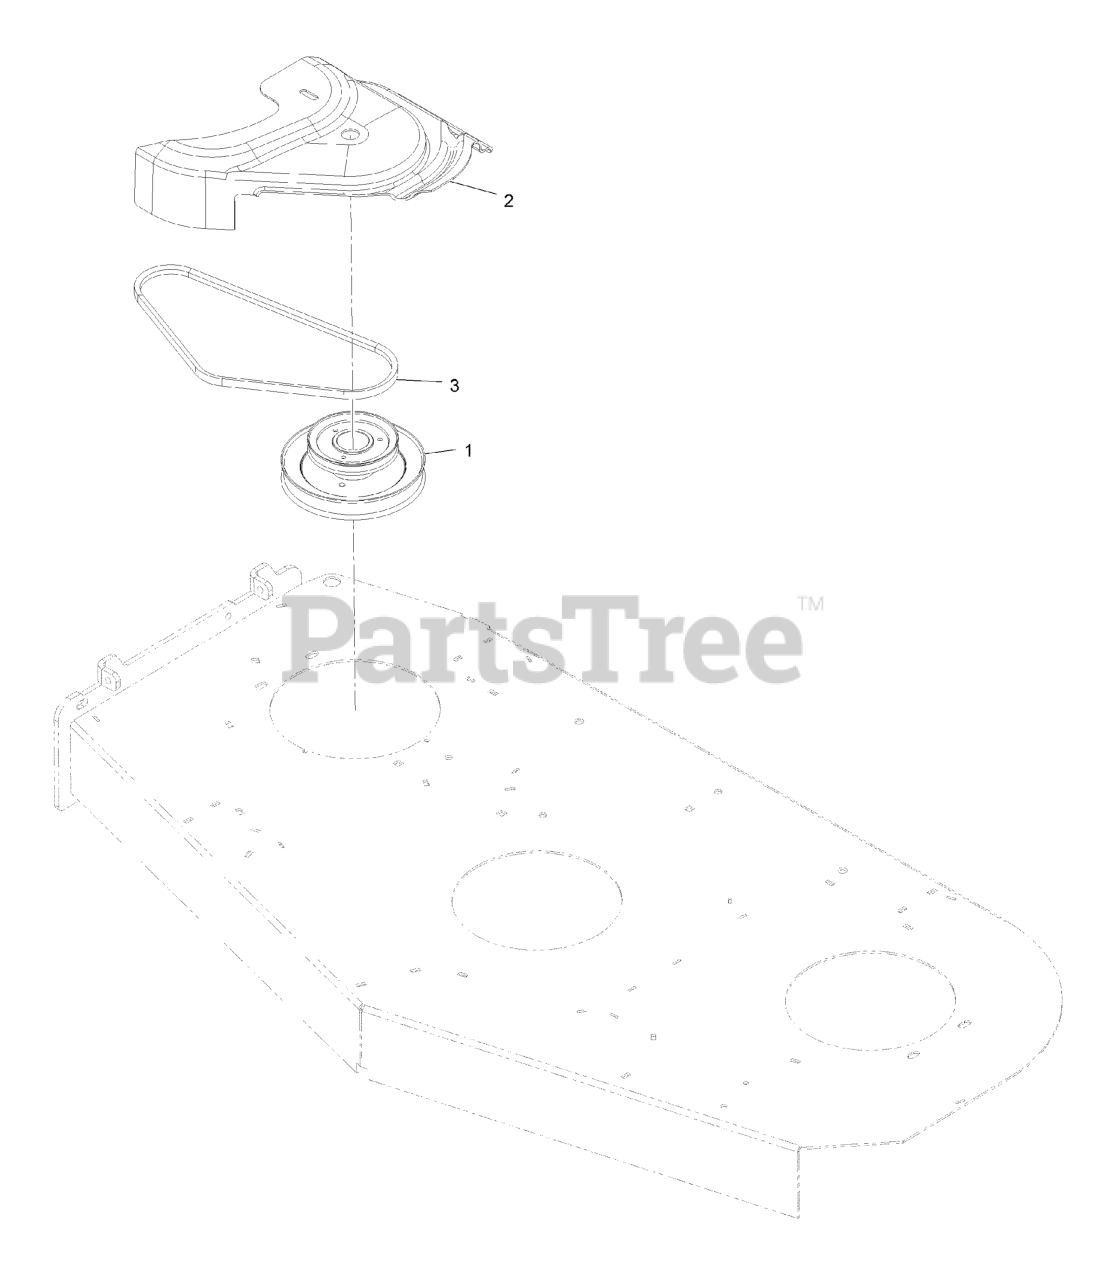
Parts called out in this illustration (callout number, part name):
1	JACKSHAFT,UV DRIVE 604 SPLINED
2	COVER,BELT DUV 60
3	BELT, BLOWER DRIVE 60
